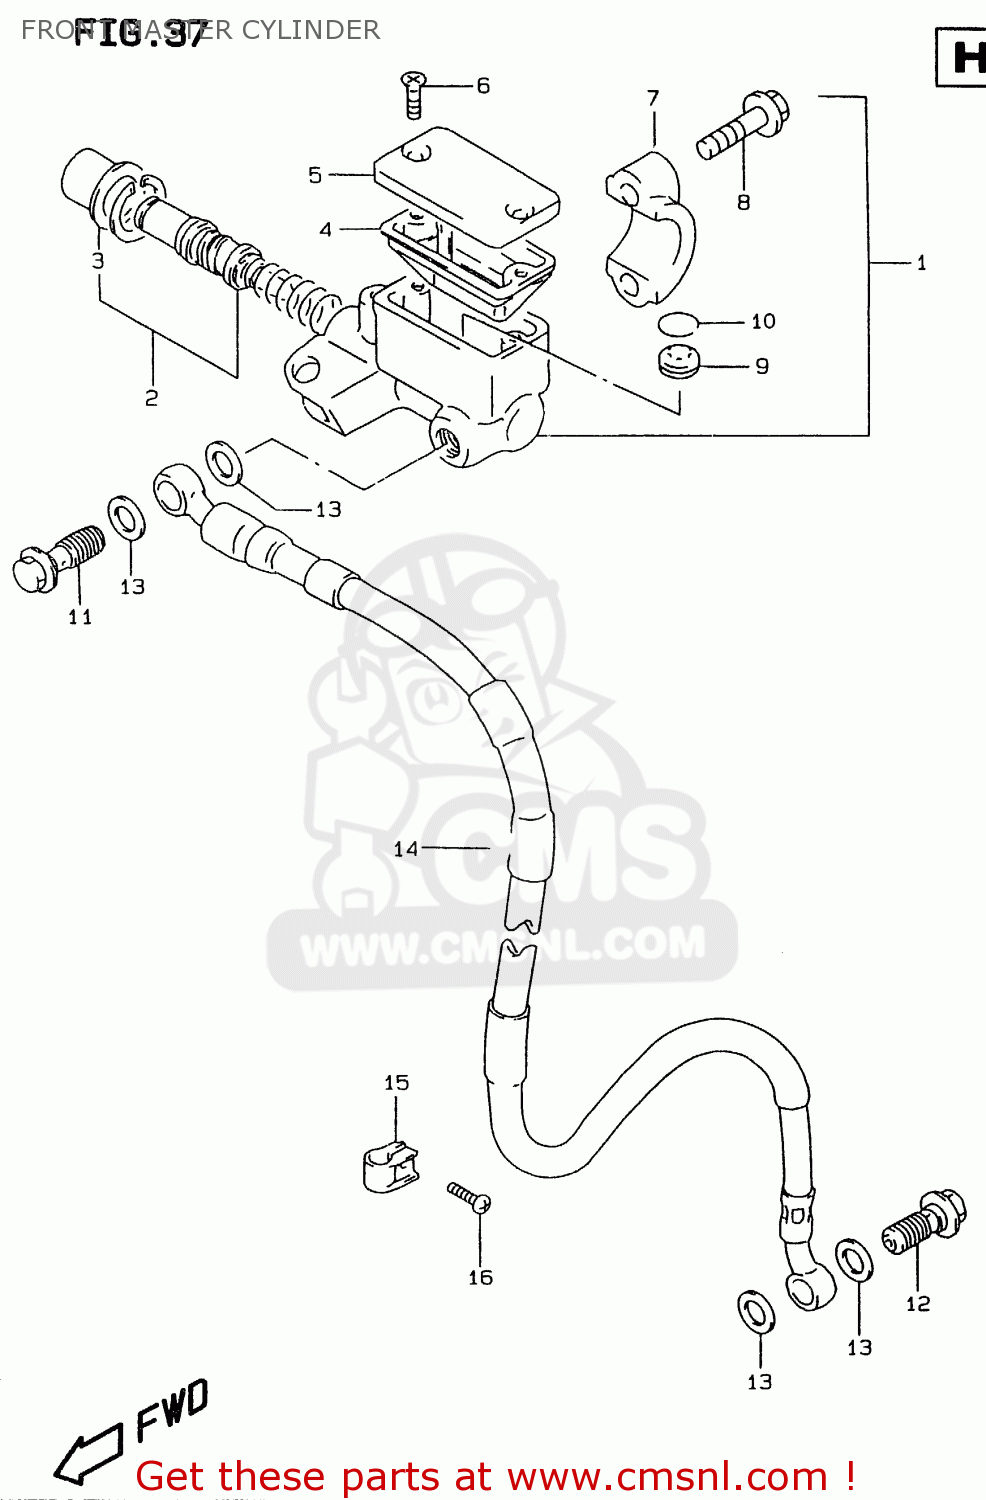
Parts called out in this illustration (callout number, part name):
1	CYLINDER ASSY,FR MASTER
2	PISTON & CUP SET
3	BOOT
4	DIAPHRAGM
5	CAP
6	SCREW
7	HOLDER
8	BOLT
9	SEPARATOR
10	RING
11	BOLT UNION
12	BOLT UNION
13	WASHER(10X15X1.5)
14	HOSE,FR BRAKE
15	CLAMP,FR BRAKE
16	SCREW
